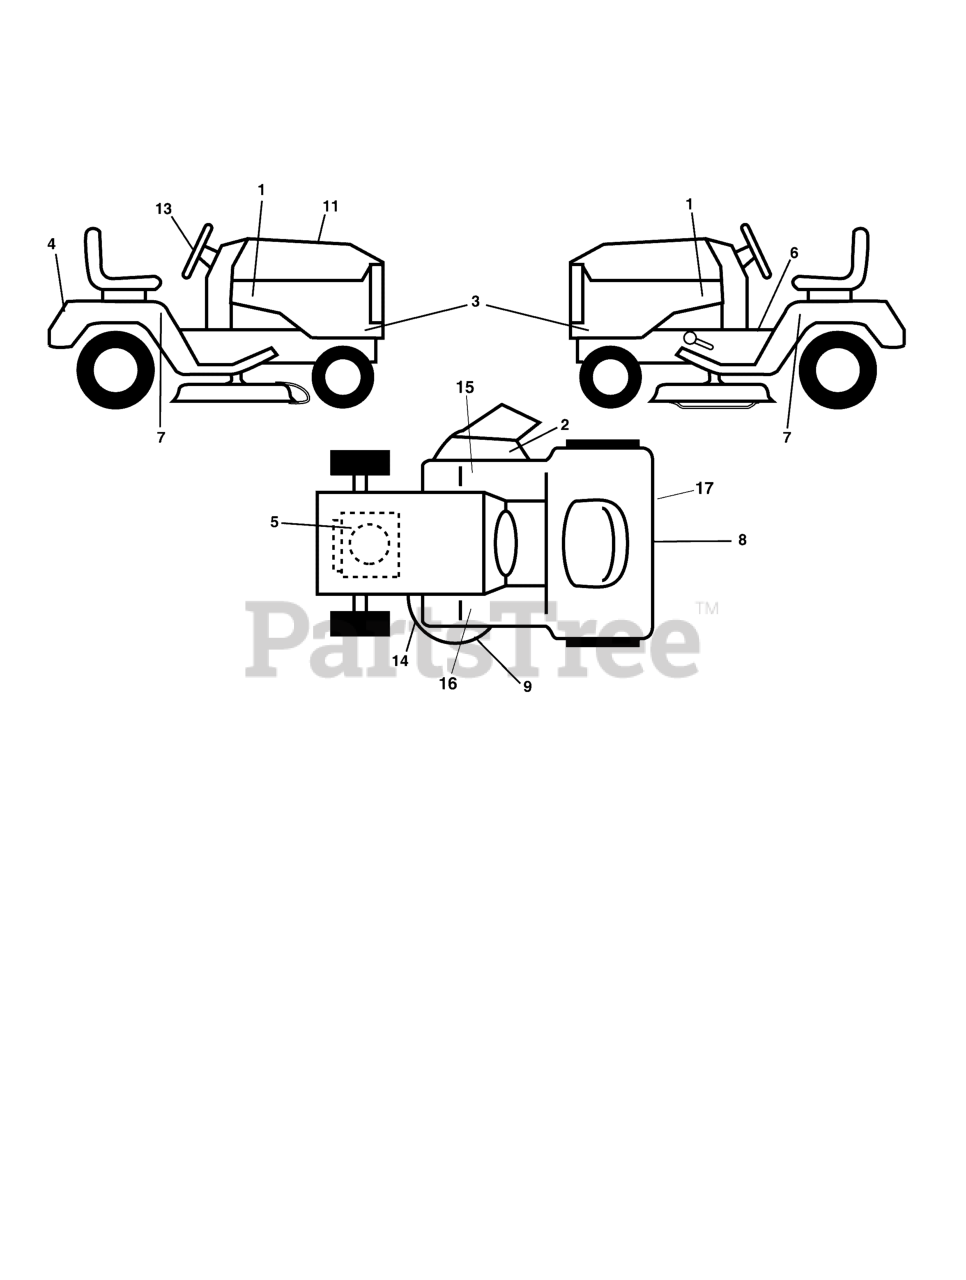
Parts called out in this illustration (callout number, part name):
1	DECAL, Snowflake Dash
2	DECAL, Keep Hand Away
3	DECAL, Side Panel
4	DECAL, Fender
5	DECAL, Engine H.P.
6	Decal, Fender Operator's
7	DECAL, 46" Deck, Fab Welded Edge
11	DECAL, Replacement
13	Decal, Steering Wheel
14	Decal, Mower Schematic
15	Pad, Footrest RH
16	Pad, Footrest, LH
17	Decal, Bypass
